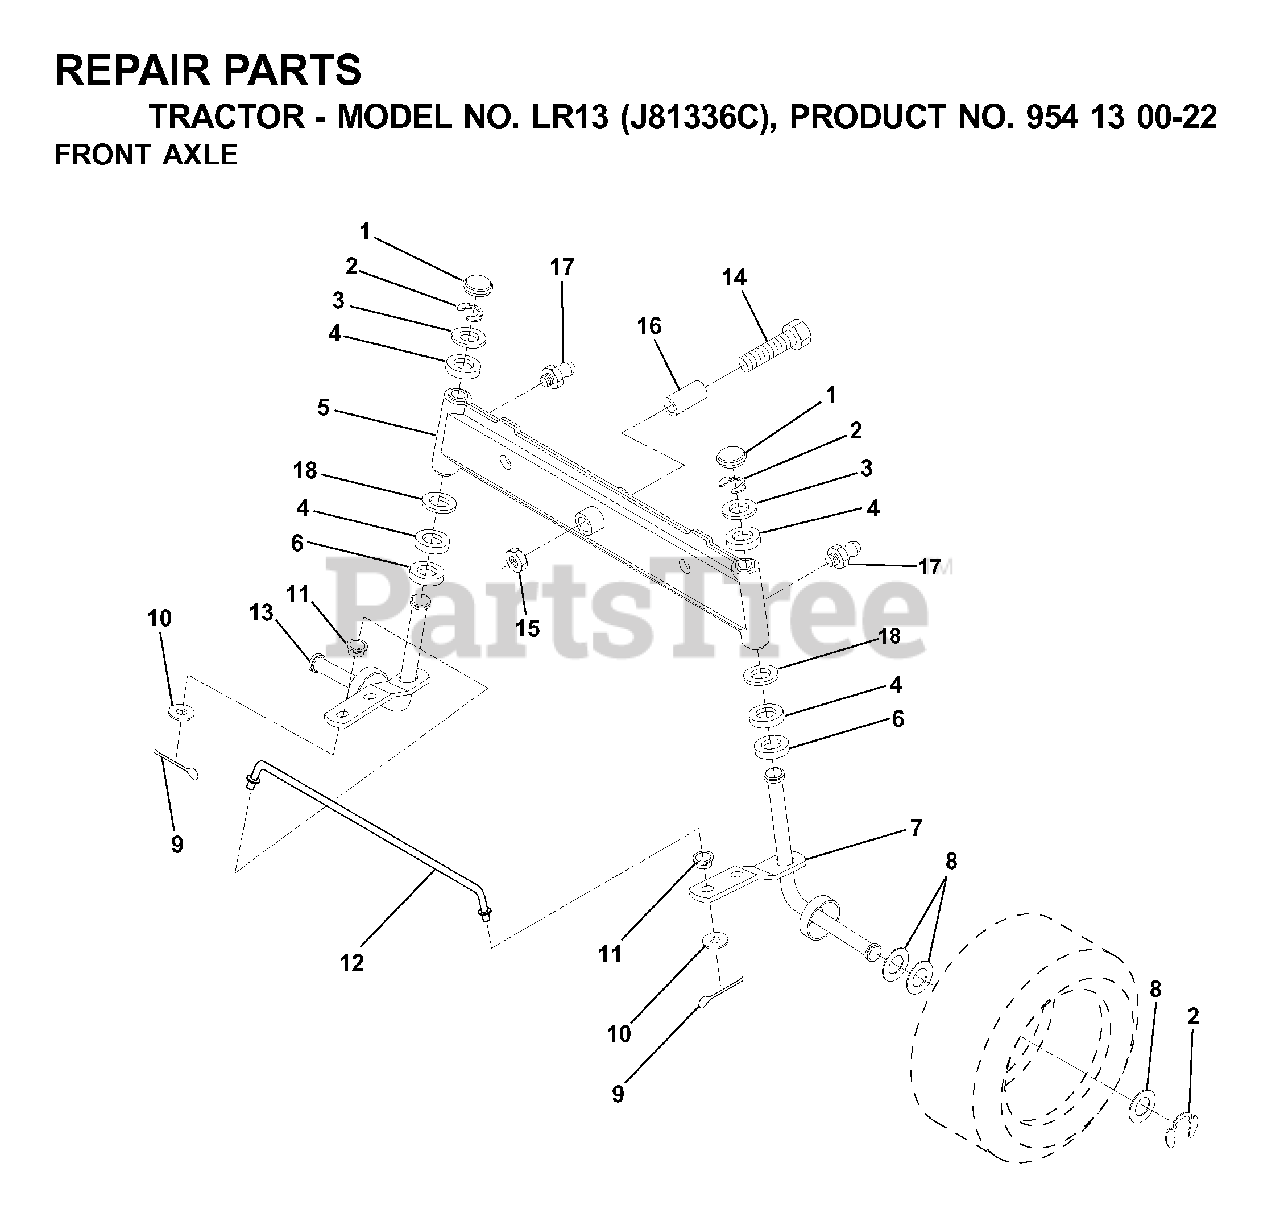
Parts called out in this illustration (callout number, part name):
1	CAP.SPINDLE
2	RING CLIP
4	BRNG T
5	AXLE ASSY
9	COTTER PIN
11	BUSHING.DRAGLINK
12	TIE ROD
13	SPINDLE.ASSEM.LH
14	BOLT.HEX.5/8-11
15	NUT-LOC,FLANGE LT
16	BEARING
17	ZERK M
